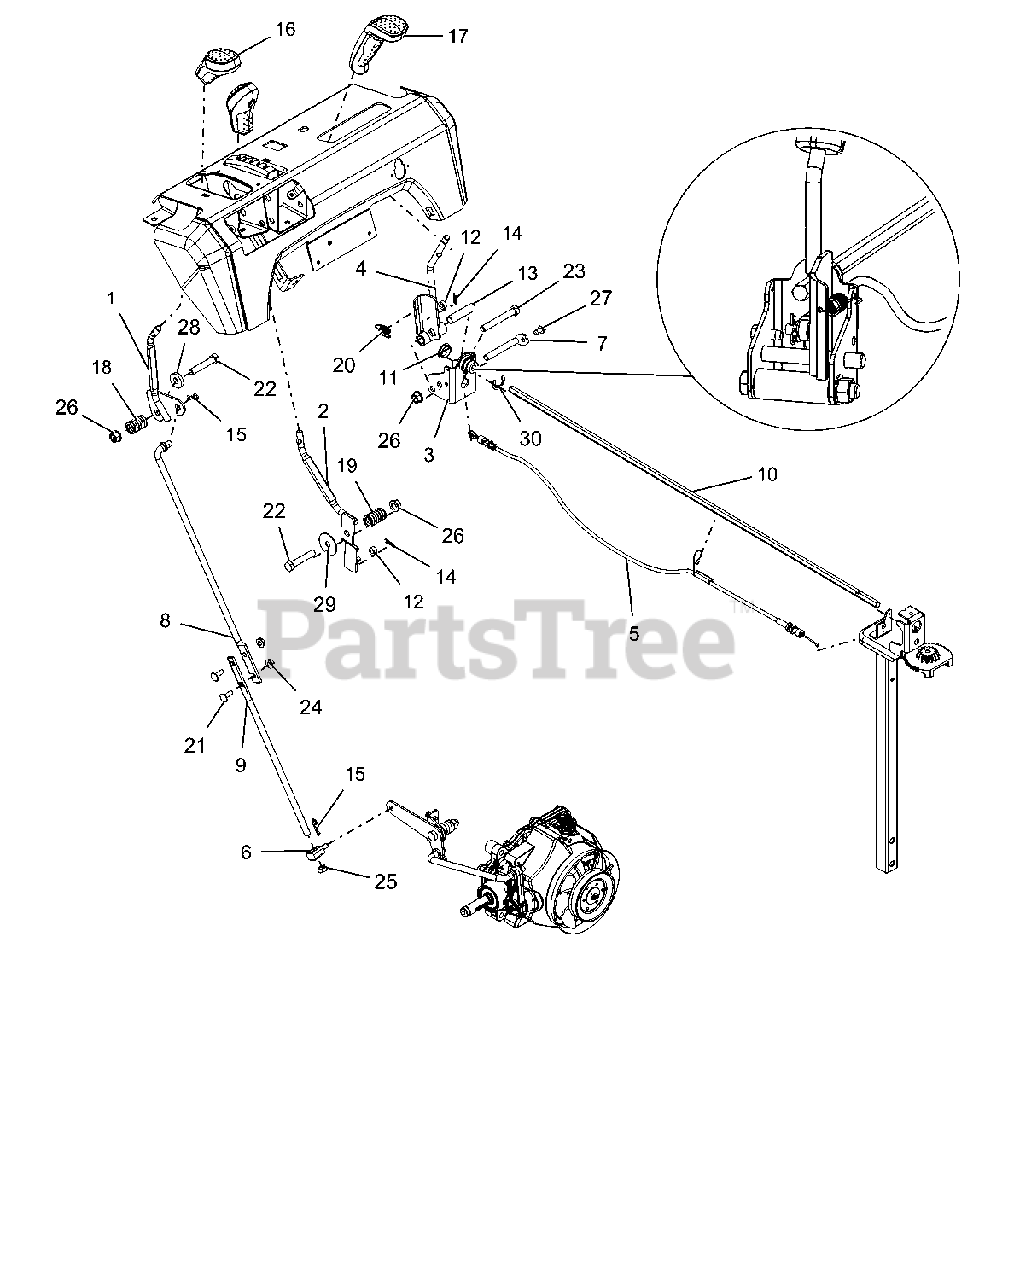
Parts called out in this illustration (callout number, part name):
1	WELDMENT,LG DASH SPEED CONTROL
2	WELDMENT,LG DASH DEFL CONTROL
3	WELDMENT-CONTROL BRACKET-CHUTE
4	WELDMENT,LG DASH QT CONTROL
5	CABLE, CHUTE LOCK, PRO
6	PIVOT,SHIFT ROD .375-16(TRUNN)
7	ROD, PIVOT - INTERLOCK
8	ROD, SHIFT - UPPER
9	ROD. HYDRO SHIFT - LOWER
10	ROD, HEX - CHUTE ROTATION
11	BUSHING, POLYLINER-.75 SNAPIN
12	BSHG-SLV .265X.500X.219
13	SPCR, WHEEL .385X.500X2.00
14	PIN-HAIR INT .06X.18X.77
15	PIN-HAIR INT .08X.18X1.18 YWZC
16	KNOB, CONTROL, DASH
17	HANDLE, QUICK TURN, ASM
18	SG-COMP .125X.781X1.250
19	SG-COMP .125X.781X1.250
20	SPRING-EXT .047X.438X1.45
21	@BLT-RDHDSQNK .25-20X.75 G5YZ
22	@BLT-HEX .38-16X2.00 GR5 YWZC
23	@BLT-HEX .38-16X2.75 GR5 YWZC
24	@NUT-LK-CTR-FLG .25-20 YWZC
25	NUT-HEX-JAM .375-16 YWZC
26	@NUT-LK-TOP-FLG .38-16 YWZC
27	SCR-TAP .25-20X.50 HWH TR YWZ
28	WSHR-FL-STL .406X1.00X.188 YWZ
29	WSHR-FL-STL .380X1.50X.062 YWZ
30	E-RING .750X.050
